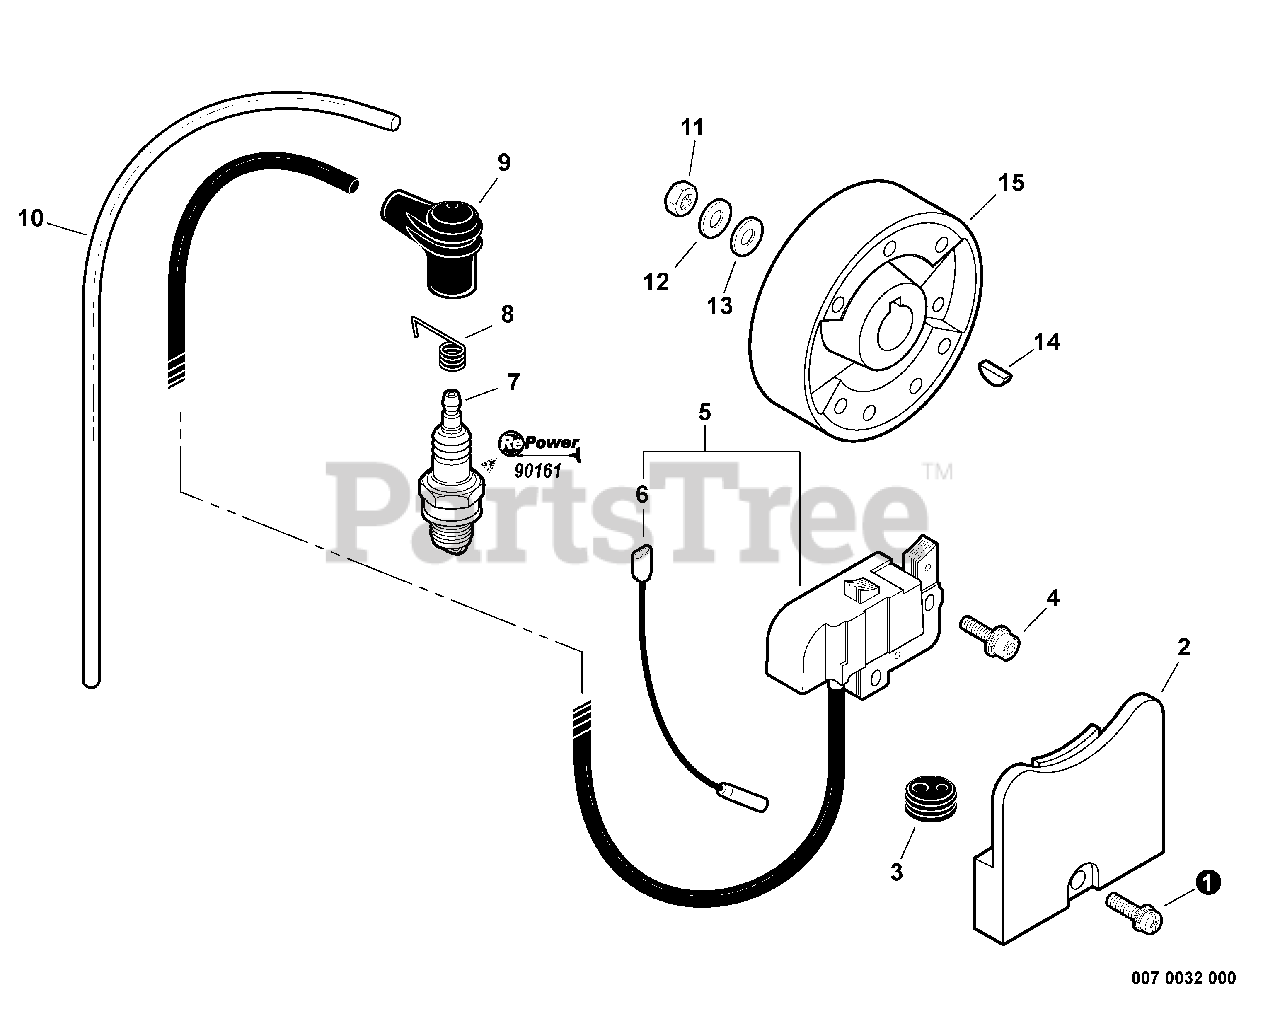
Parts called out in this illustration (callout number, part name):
1	SCREW 5×18
2	COVER, DUST
4	SCREW 5×18
5	COIL, IGNITION
6	LEAD - GROUND
7	SPARK PLUG - BPM8Y
7	SPARK PLUG - BPMR8Y
8	TERMINAL, SPARK PLUG
9	CAP, SPARK PLUG
10	TUBE, VINYL 6.3×8×380
12	WASHER, SPRING 10
13	WASHER, SPRING 10
14	KEY, WOODRUFF 3×14
15	FLYWHEEL
16	TUNE-UP KIT - REPOWER
